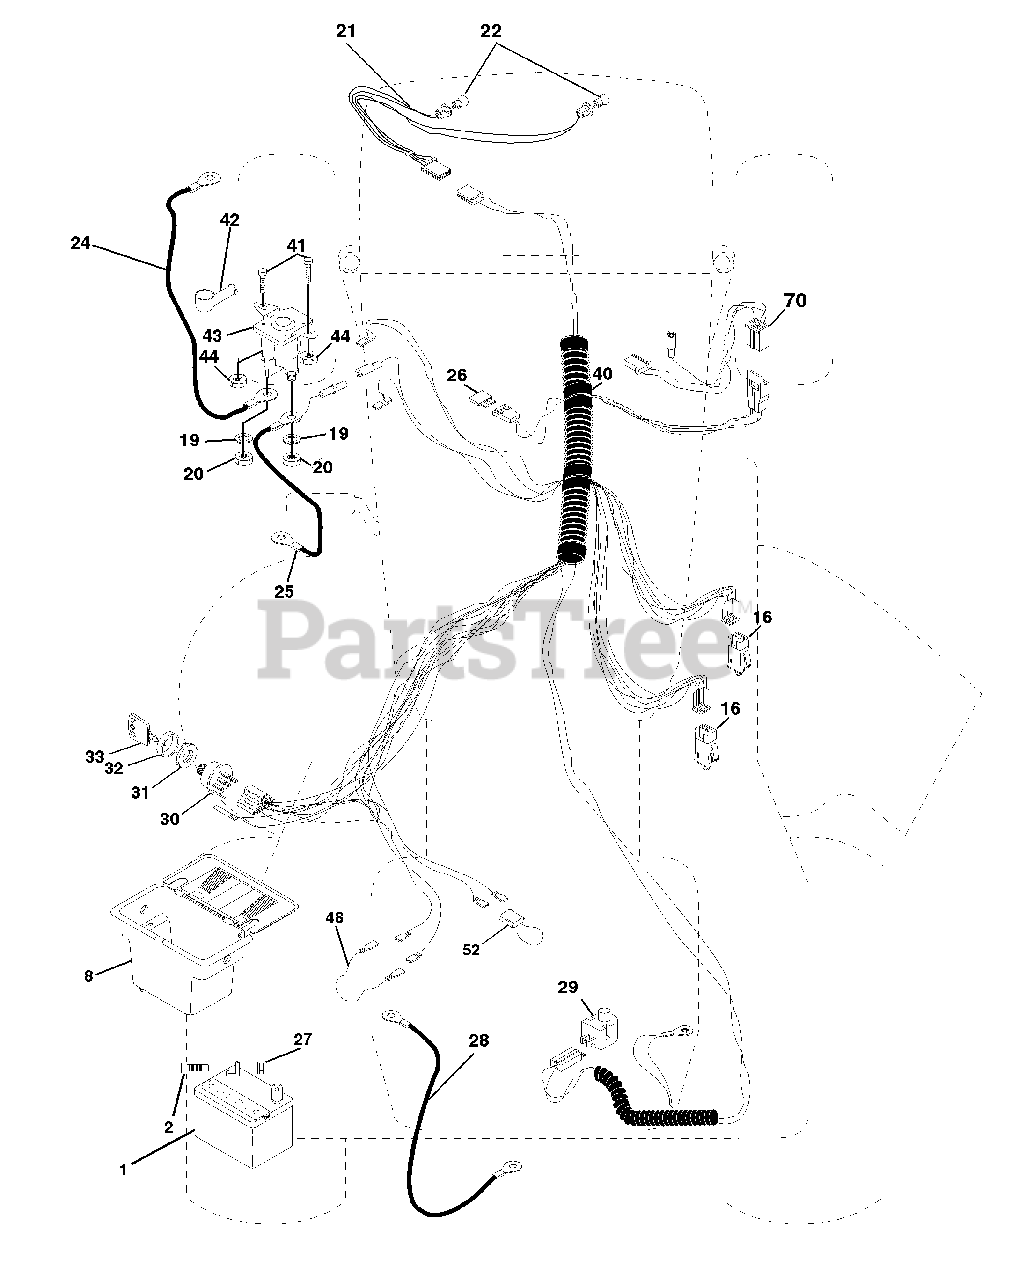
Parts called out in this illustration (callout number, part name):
1	Battery 12 Volt 25 AMP
2	Bolt Hex Hd 1/4-20unc X 3/4
8	Case Battery Mech Hinge
16	Switch Interlock Push-In
19	Washer Lock 1/4
20	Nut Jam Hex 1/4-20 Unc
21	Harness Asm Light W/4152j
22	Bulb Light #1156
24	Cable Battery 6 Ga 11" red
25	Cable Battery 6 Ga 44" red w/16 wire
26	Fuse 15 AMP
27	Nut Keps Hex 1/4-20 Unc
28	Cable Ground 6 Ga 12" black
29	Switch Plunger Nc Gray
30	Switch Ign 4 pos w/lights
31	Nut Ignition
32	Cover Sw Ignition
33	Key Ign Molded Generic
40	Harness Ign.
41	Bolt Blk Fin Hex 1/4-20 x 1/2
42	Cover Terminal Red
43	Solenoid
44	Nut Keps Hex 1/4-20 Unc
48	Adapter Ammeter Rectangular
52	Protection Wire Loop
70	Harness, Eng. B&S
